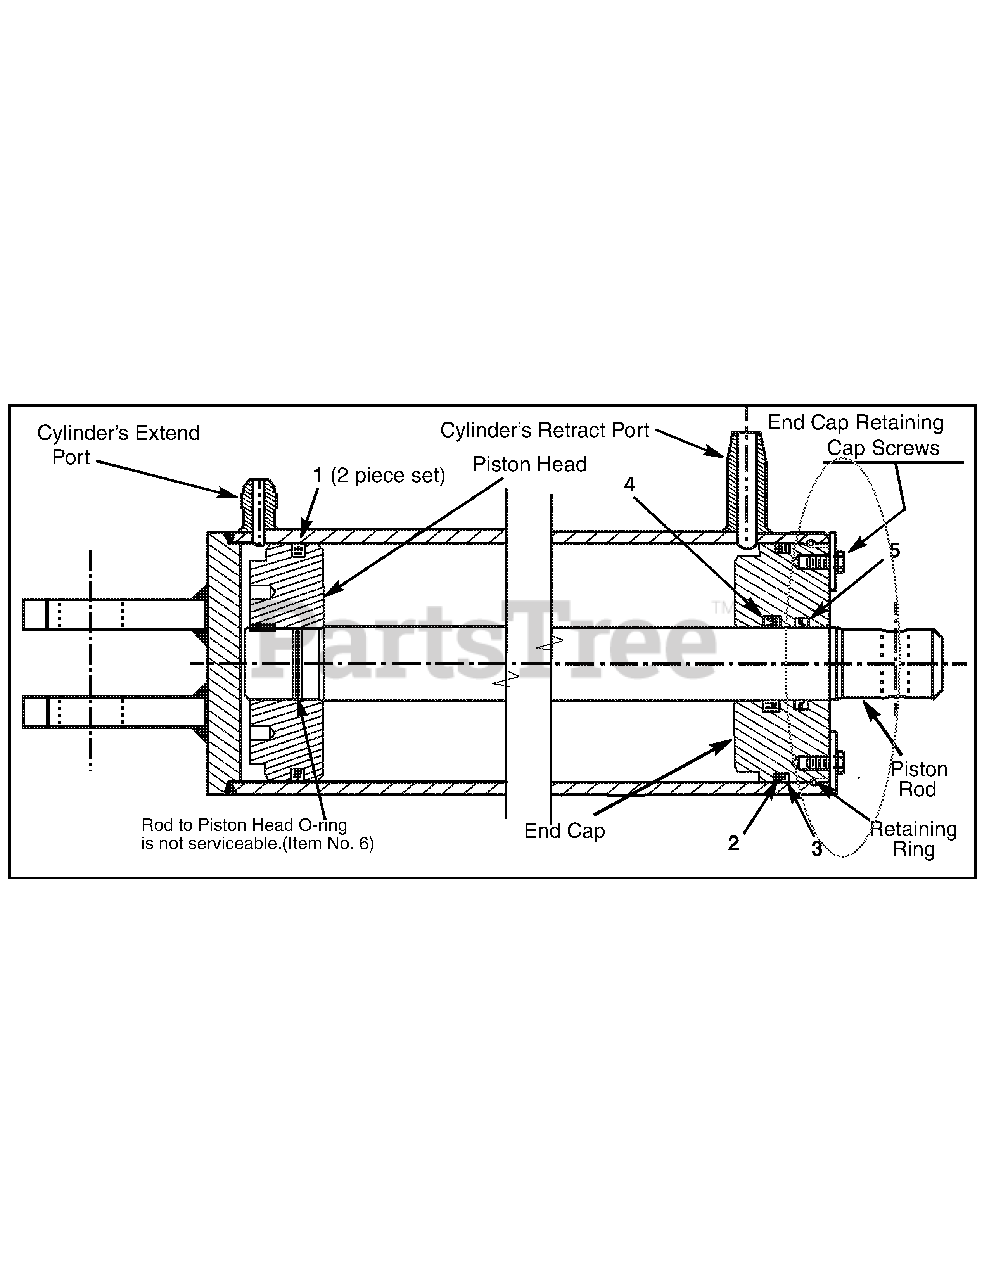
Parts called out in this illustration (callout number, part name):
1	Piston Seal: 2 piece set (White outer ring w/ black flat under ring)
2	O-ring (Large, Black)
3	Backup Ring (Black)
4	Rod-Guide U-Cup (Dark Blue)
5	Scraper: Rod (Black)
6	O-ring (Small, Black) NOT USED
7	INSTRUCTION SHEET
